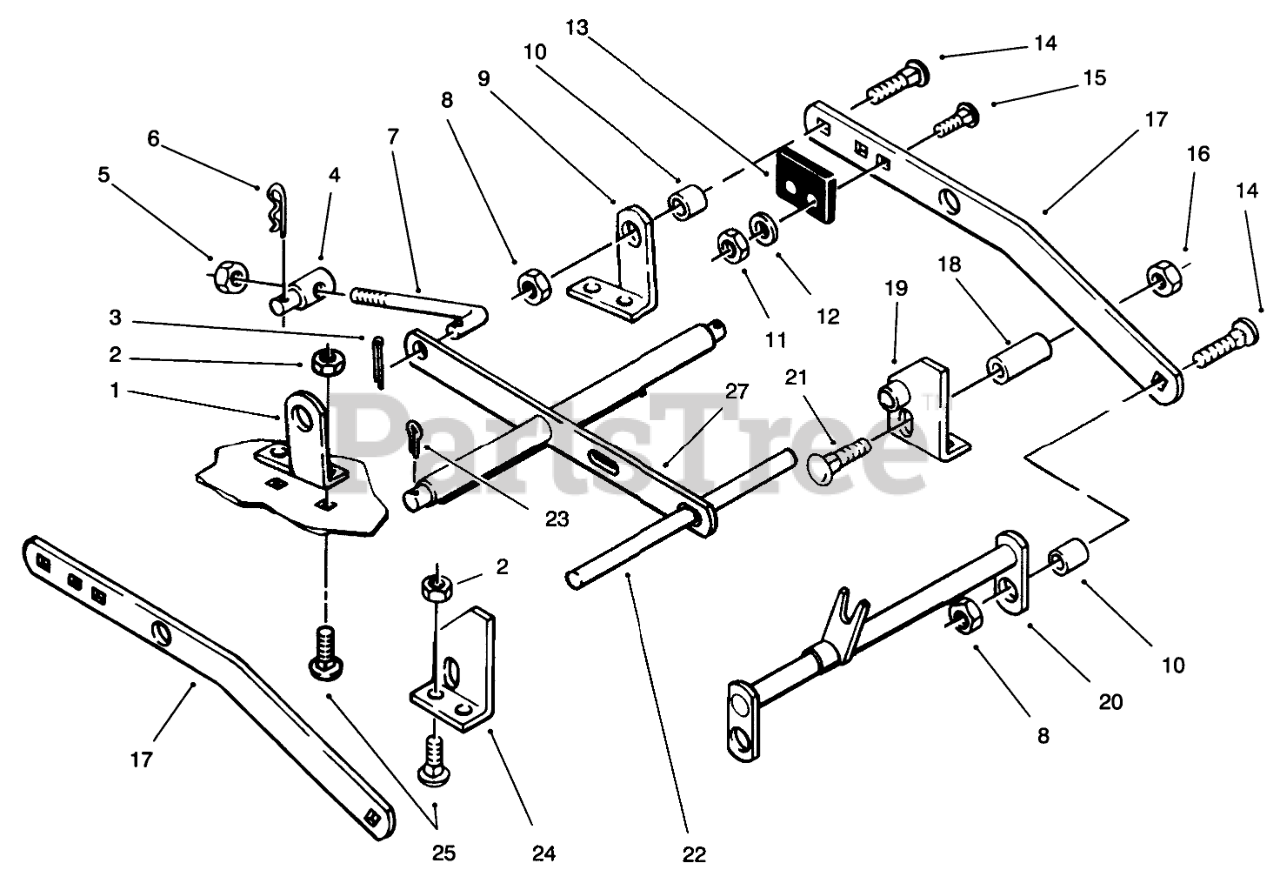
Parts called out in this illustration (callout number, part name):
1	Rear Bracket RH
2	NUT-LOCK, NI
3	PIN-COTTER
4	TRUNNION-LIFT
5	NUT-LOCK, NI
6	PIN-HAIR
7	ROD-LEVEL ADJUST
8	LOCKNUT-FLANGE
9	LH Rear Bracket
10	SPACER
11	NUT-LOCK, NI
12	WASHER-FLAT
13	BUMPER
14	BOLT-CARR
15	SCREW-CARR
16	NUT-LOCK, NI
17	Bar Draft
18	SPACER
19	Front Bracket LH
20	Hitch
21	BOLT-CARR
22	Front Shaft
23	PIN-COTTER
24	Front Bracket RH
25	BOLT-CARR
27	Leveler
